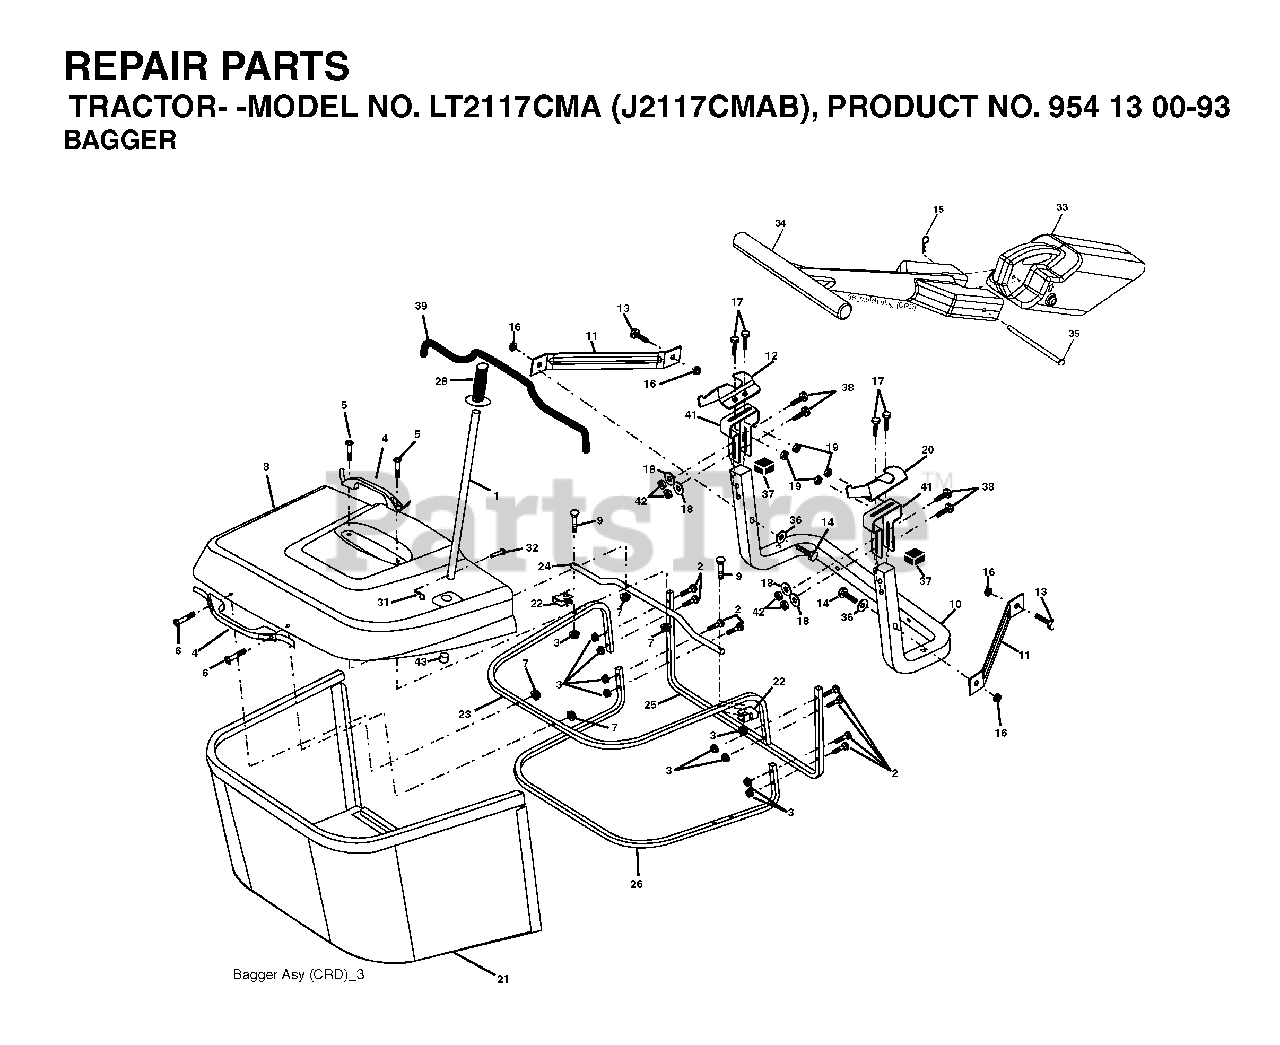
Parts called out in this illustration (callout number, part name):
1	TUBE HANDLE
3	NUT T
5	SCREW.PAN.HEAD
11	BRACKET
14	BOLT-HEX EAK
15	RETAINER-SPRNG RB
16	NUT LOCK FLG 3/8-16 UNC
17	BOLT
18	WASHER M
19	NUT LOCK HEX FLANGE 5/16-18
20	BRACKET
21	GRASS BAG
22	BRACKET
23	TUBE
24	TUBE
26	TUBE
28	GRIP.HANDLE.BLACK
31	RETAINER M
32	RIVET,DRILLED
33	MULCH PLUG, CTH150
35	PIN
36	WASHER
38	BOLT.5/16-18X2.5
41	BRKT, BAGGER
42	NUT.71038.31-18.HEX.NYLOCK
43	PLUG, TUBING END
